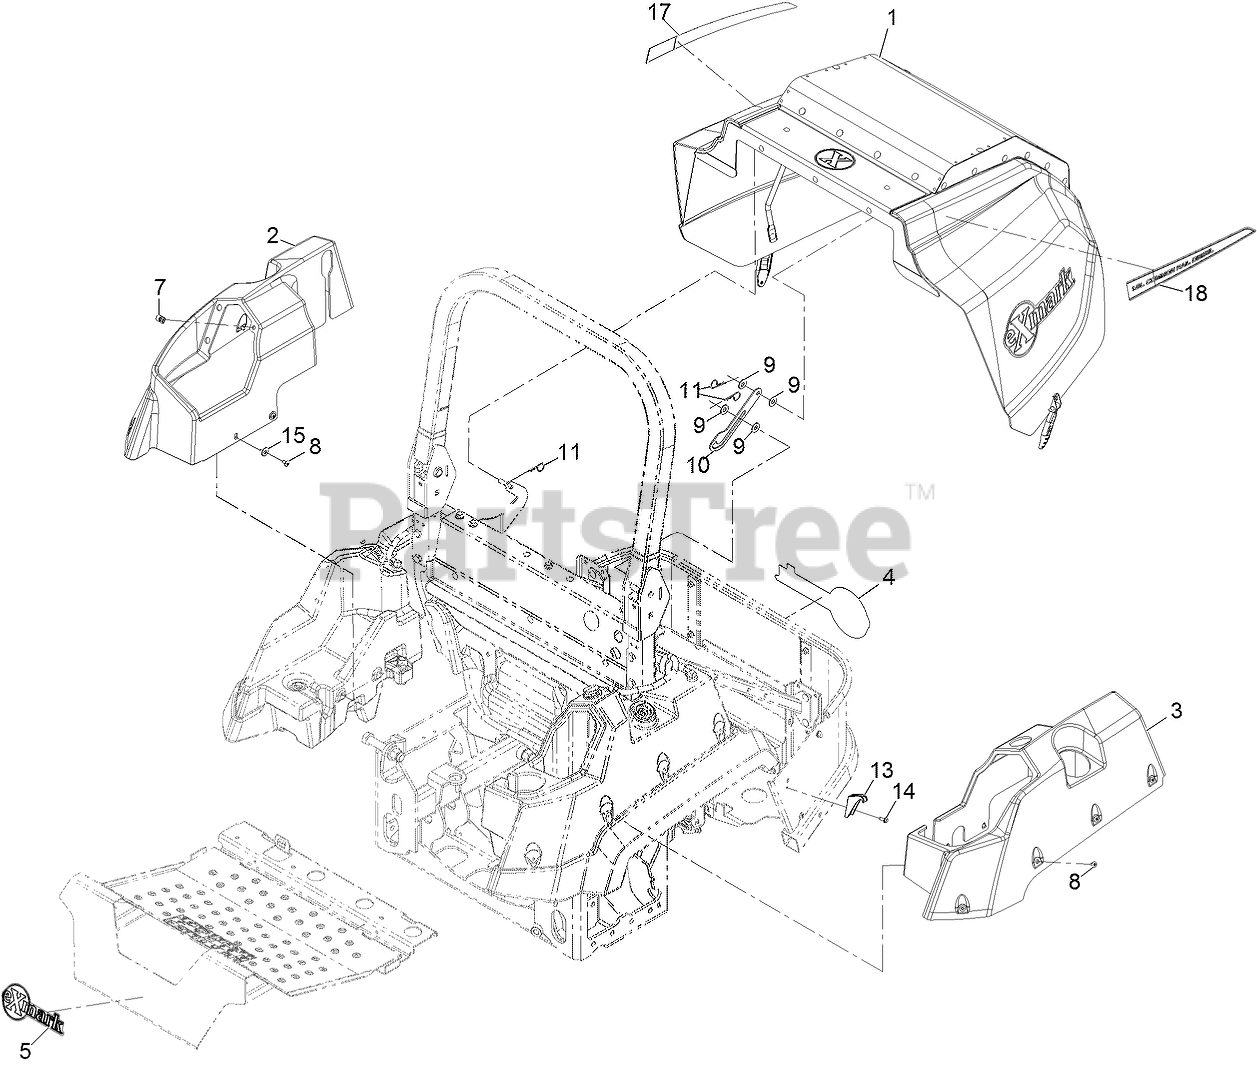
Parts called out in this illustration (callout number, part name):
1	ASM, HOOD LZSD
2	COVER-TANK, RH
3	COVER-TANK, LH
4	DECAL-EXMARK
5	DECAL-EXMARK
8	SCREW-TORX
9	WASHER-FLAT
10	PROP-HOOD
11	PIN-COTTER, HAIR
13	LATCH-CATCH
14	SCREW-HWH
15	WASHER-FLAT
17	DECAL-TURBO DIESEL-RH
18	DECAL-TURBO DIESEL-LH
